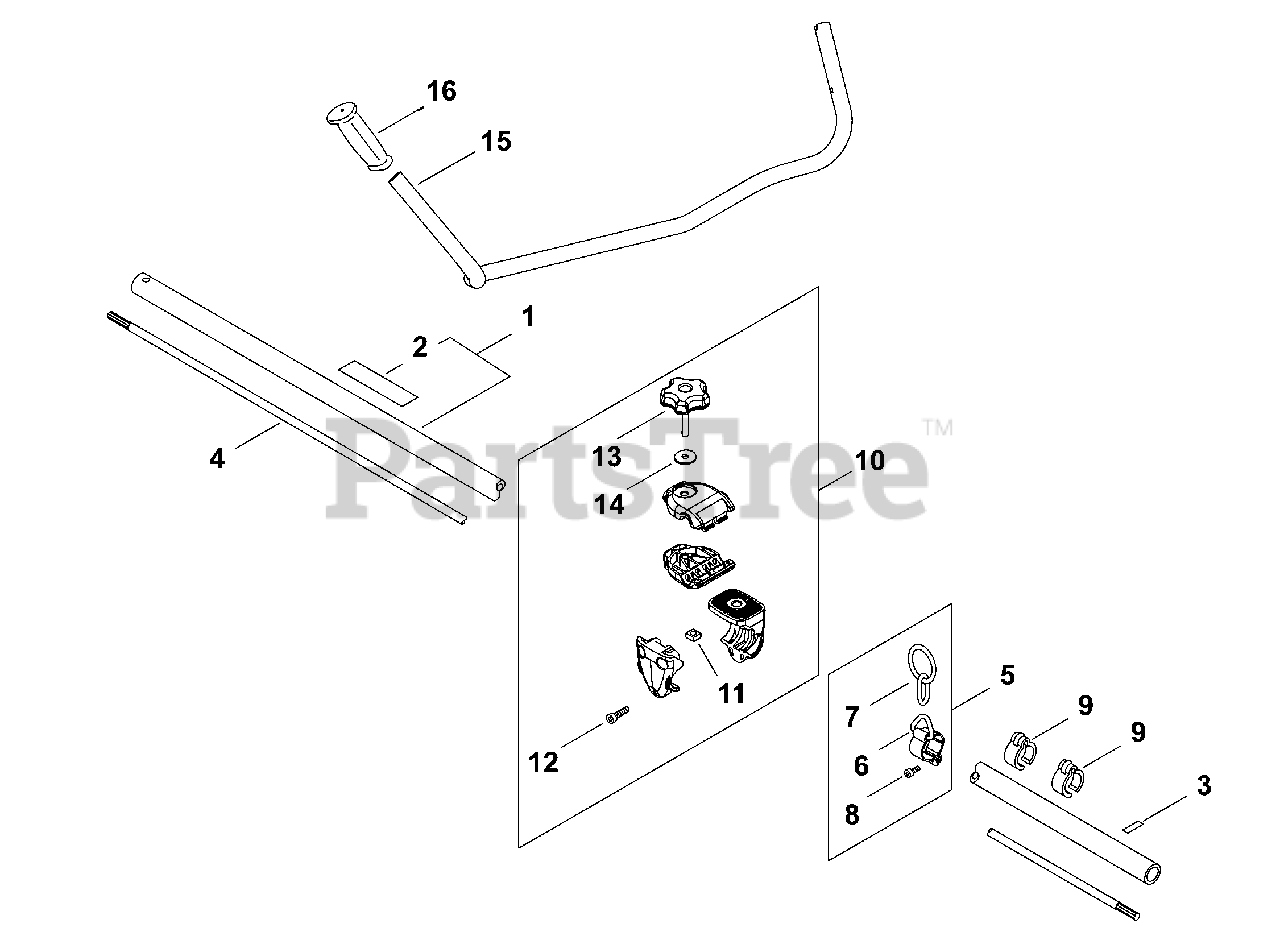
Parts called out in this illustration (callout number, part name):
1	MAIN PIPE ASSY
2	LABEL, CAUTION - ISO
3	LABEL - ALIGNMENT
4	DRIVESHAFT
5	HANGER ASSY, HARNESS
6	HANGER, HARNESS
7	RING, HARNESS
8	BOLT 5×12
9	CLIP 28 MM
10	MOUNTING KIT, HANDLEBAR
11	NUT 8×1.25
12	BOLT 5×30
13	KNOB, SCREW M8
14	WASHER 8
15	HANDLEBAR
16	GRIP, HANDLE
